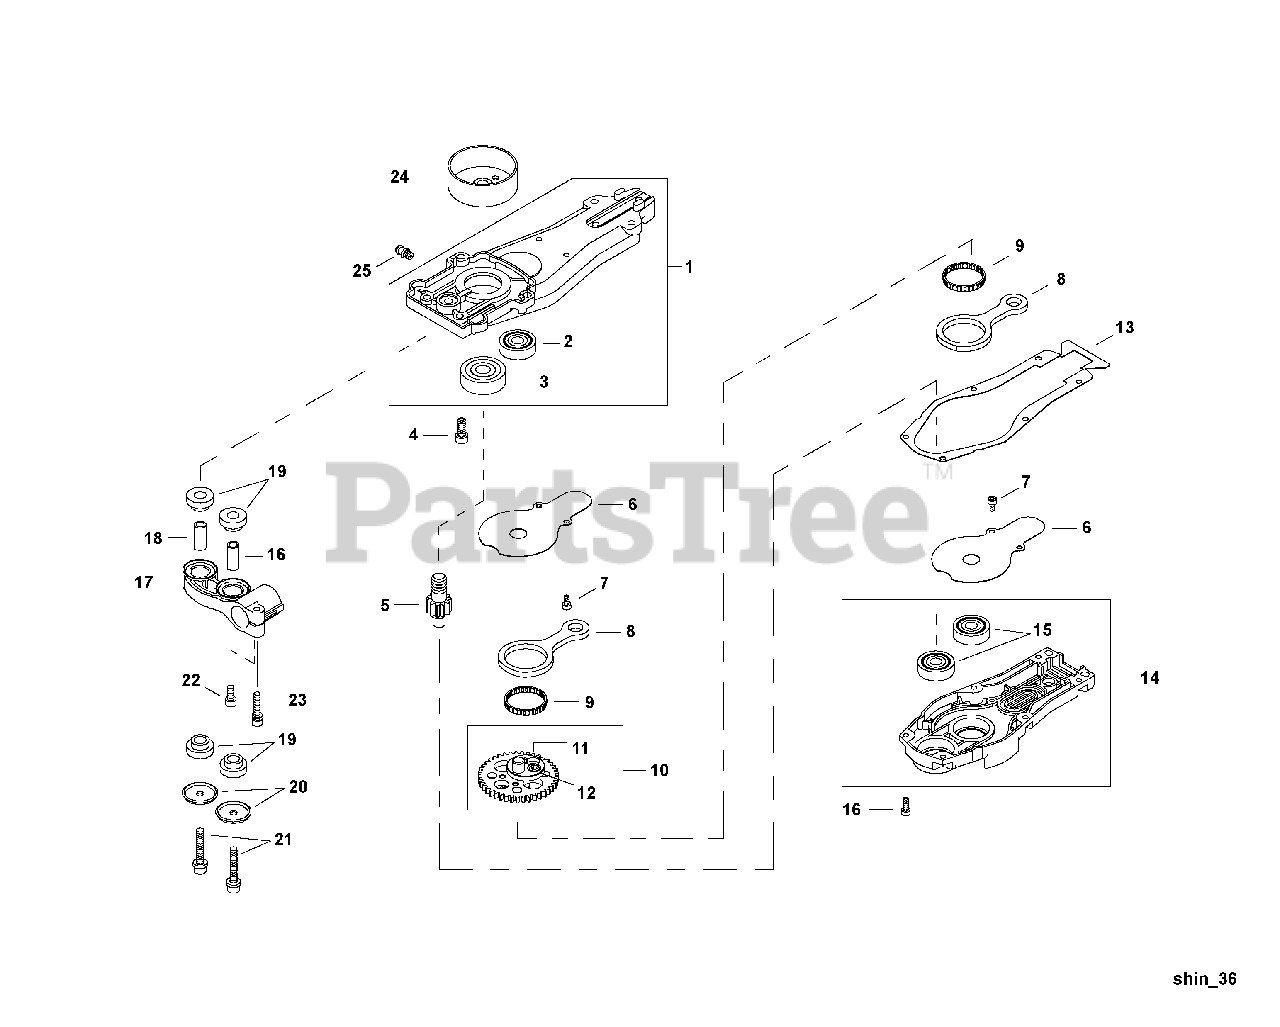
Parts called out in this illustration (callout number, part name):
1	GEAR CASE ASSY
2	BEARING, BALL - 6200ZZ
3	BEARING, BALL - 6301DDU
4	SCREW - 6X16
5	GEAR - PINION
6	PLATE, GEAR CASE
7	SCREW - 4X8
8	ROD, CONNECTING
9	BEARING, NEEDLE - 30
10	CAM GEAR ASSY
11	SCREW - 5X6
13	GASKET, GEAR CASE
14	GEAR CASE COVER ASSY
15	BEARING, BALL - 6200ZZ
16	SCREW - 4X14
17	MOUNT, HANDLE
18	COLLAR - 6
19	CUSHION
20	WASHER - CUP
21	SCREW - 6X35
22	SCREW - 5X12
23	SCREW - 5X25
24	DRUM, CLUTCH
25	FITTING, GREASE
